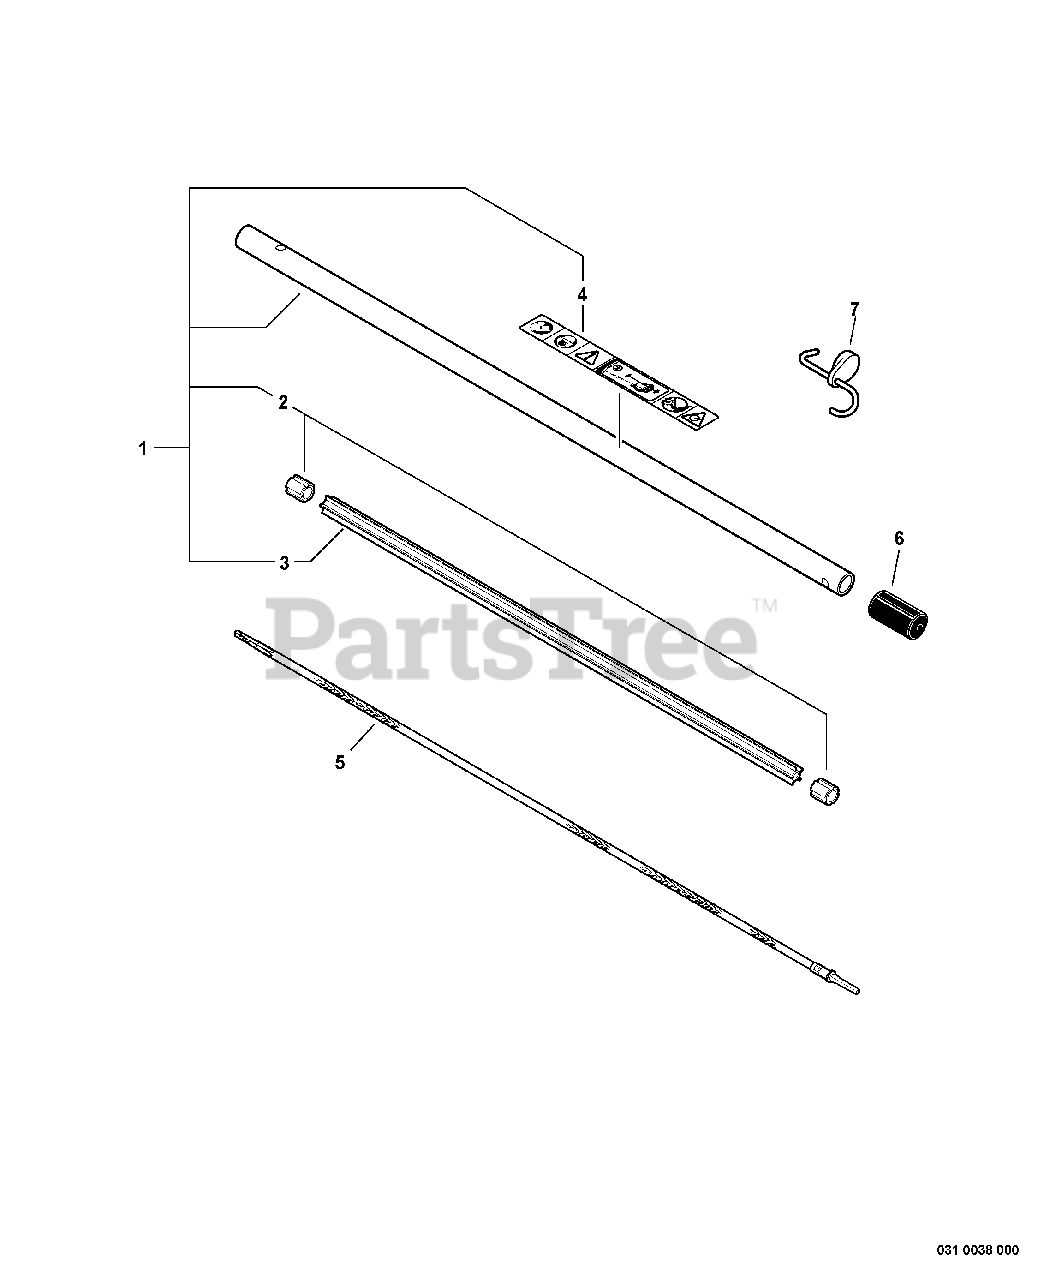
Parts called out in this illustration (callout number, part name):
1	MAIN PIPE ASSY
3	LINER - FLEXIBLE
4	LABEL - CAUTION
5	DRIVESHAFT - FLEXIBLE
7	PAS ATTACHMENT HANGER
